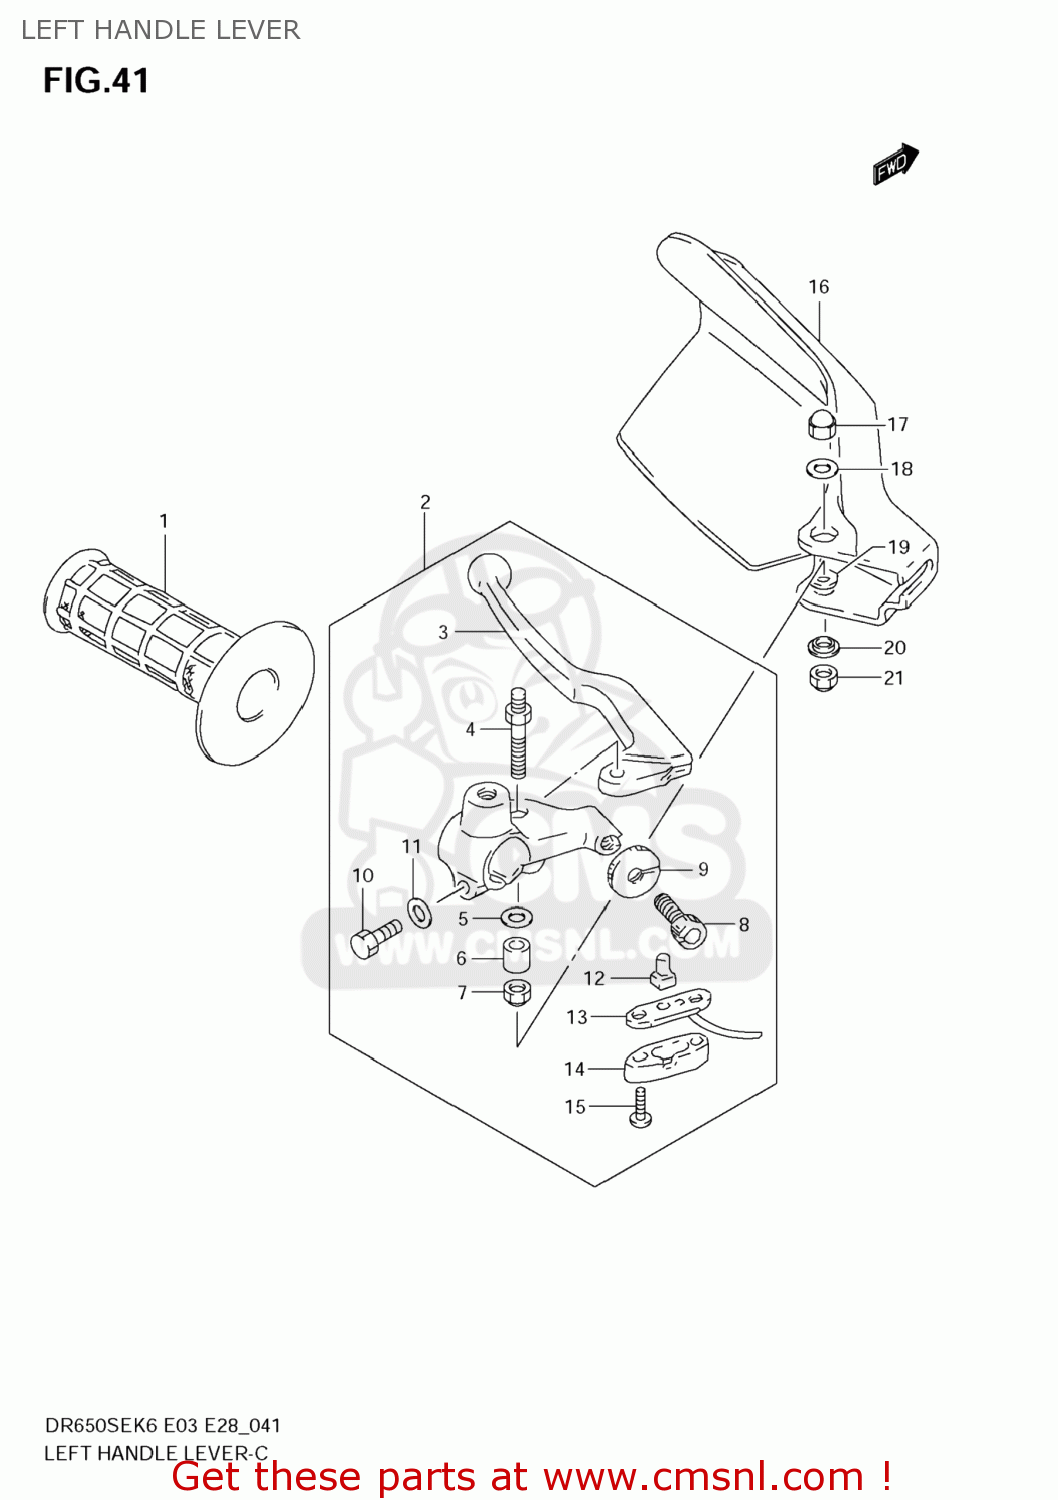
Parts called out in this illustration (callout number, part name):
1	GRIP,L
2	LEVER ASSEMBLY,CLUTCH
3	LEVER,CLUTCH
4	BOLT,CLUTCH LEVER PIVOT
5	WASHER
6	SPACER,LEVER SET
7	NUT
8	ADJUSTER,CABLE
9	NUT,CABLE ADJUSTER LOCK
10	BOLT
11	WASHER
12	CONTACT,SWITCH
13	HARNESS ASSY,WIRE
14	COVER,FR BK TERMINAL BASE
15	SCREW
16	COVER, KNUCKLE LH (BLUE)
17	NUT
18	WASHER(6.5X20X1.6)
19	WASHER(6.5X16X1.2)
20	WASHER
21	NUT
